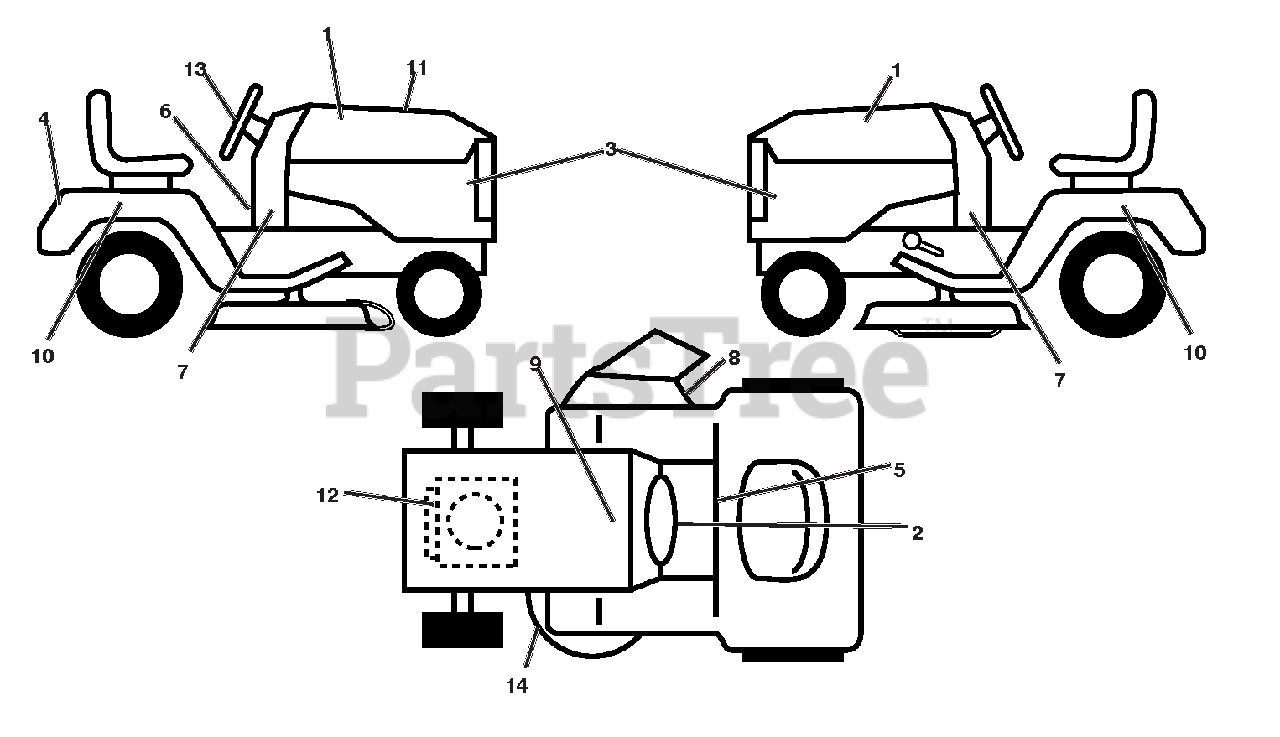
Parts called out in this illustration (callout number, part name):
1	DECAL.HOOD.LH/RH.
2	DECAL.WARNING.START
3	DECAL.SDPNL.PWRDBY B&S.ARIENS
4	DECAL.FENDER.REAR.ARIENS
5	DECAL.FENDER
6	DECAL.WARNING SPARK
7	DECAL.DASH TOWER
8	DECAL.MOWER.WARN.KEEP HAND AWY
9	DECAL.BAT.DAN/POI P/L SYM.WPN
10	DECAL, FENDER
11	DECAL.REPLACEMENT
12	DECAL ENGINE H.P.
13	DECAL.WHEEL.STEER.ARIENS
14	DECAL.V-BELT.SCH.
